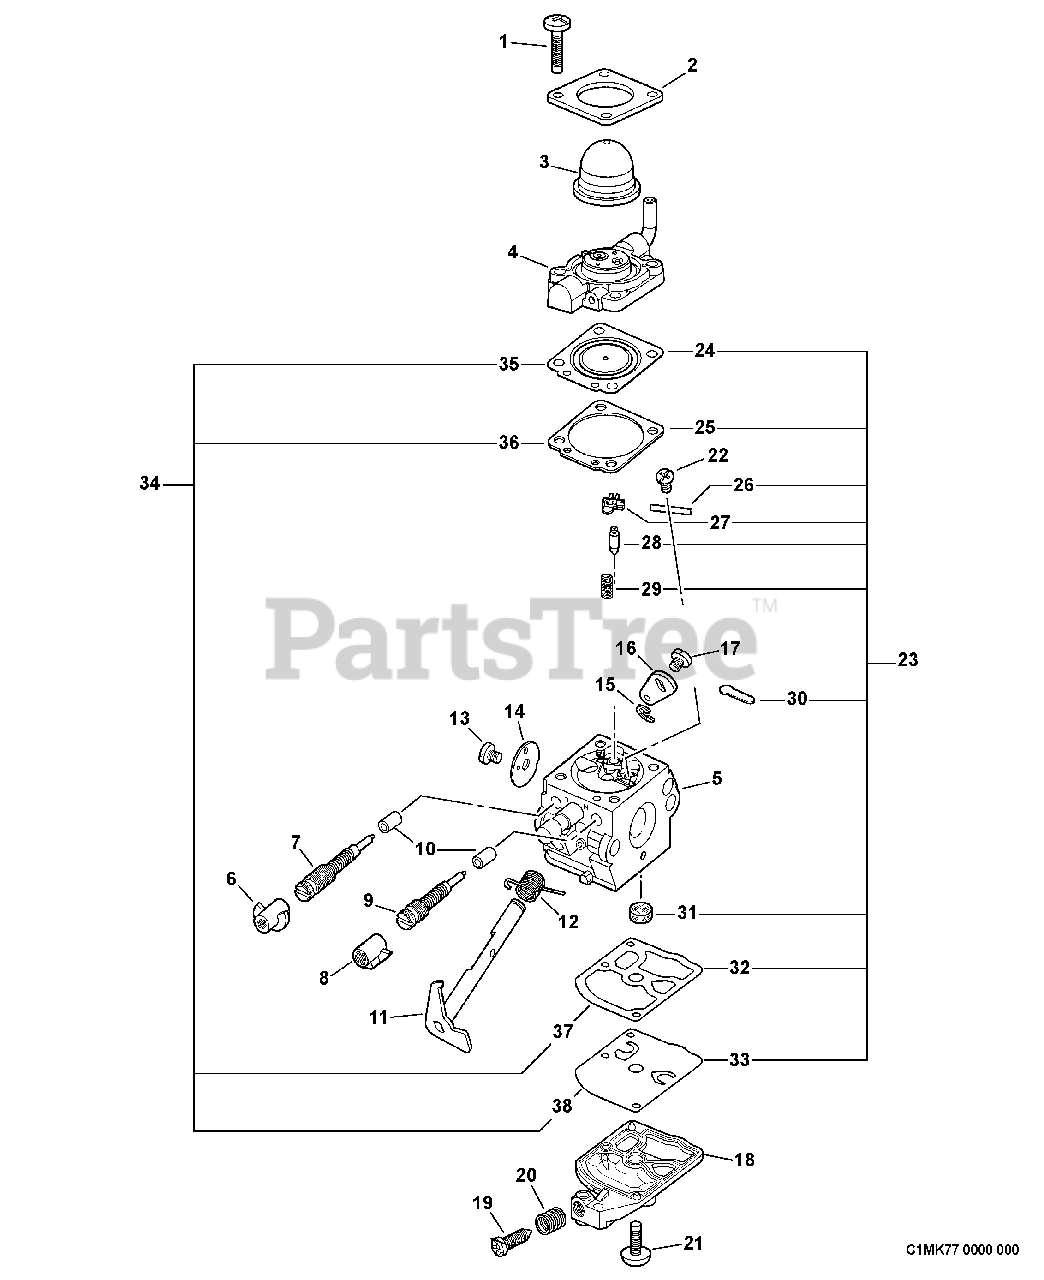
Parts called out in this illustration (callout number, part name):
2	RETAINER, PURGE BULB
3	BULB, PURGE
4	BODY ASSY, PURGE
5	BODY, CARBURETOR
6	CAP, LIMITER - WHITE
7	NEEDLE, LOW SPEED
8	CAP, LIMITER
9	NEEDLE, HIGH SPEED
10	RETAINER
11	SHAFT ASSY, THROTTLE
12	SPRING, THROTTLE RETURN
14	VALVE, THROTTLE
16	LEVER, THROTTLE
18	COVER, PUMP
20	SPRING, IDLE ADJUST
23	REPAIR KIT
24	DIAPHRAGM, METERING
25	GASKET, DIAPHRAGM
26	PIN, METERING LEVER
27	LEVER, METERING
28	VALVE, INLET NEEDLE
29	SPRING, METERING LEVER
30	PLUG, WELCH
31	STRAINER
32	DIAPHRAGM, PUMP
33	GASKET, PUMP
34	GASKET / DIAPHRAGM KIT
35	DIAPHRAGM, METERING
36	GASKET, DIAPHRAGM
37	DIAPHRAGM, PUMP
38	GASKET, PUMP
